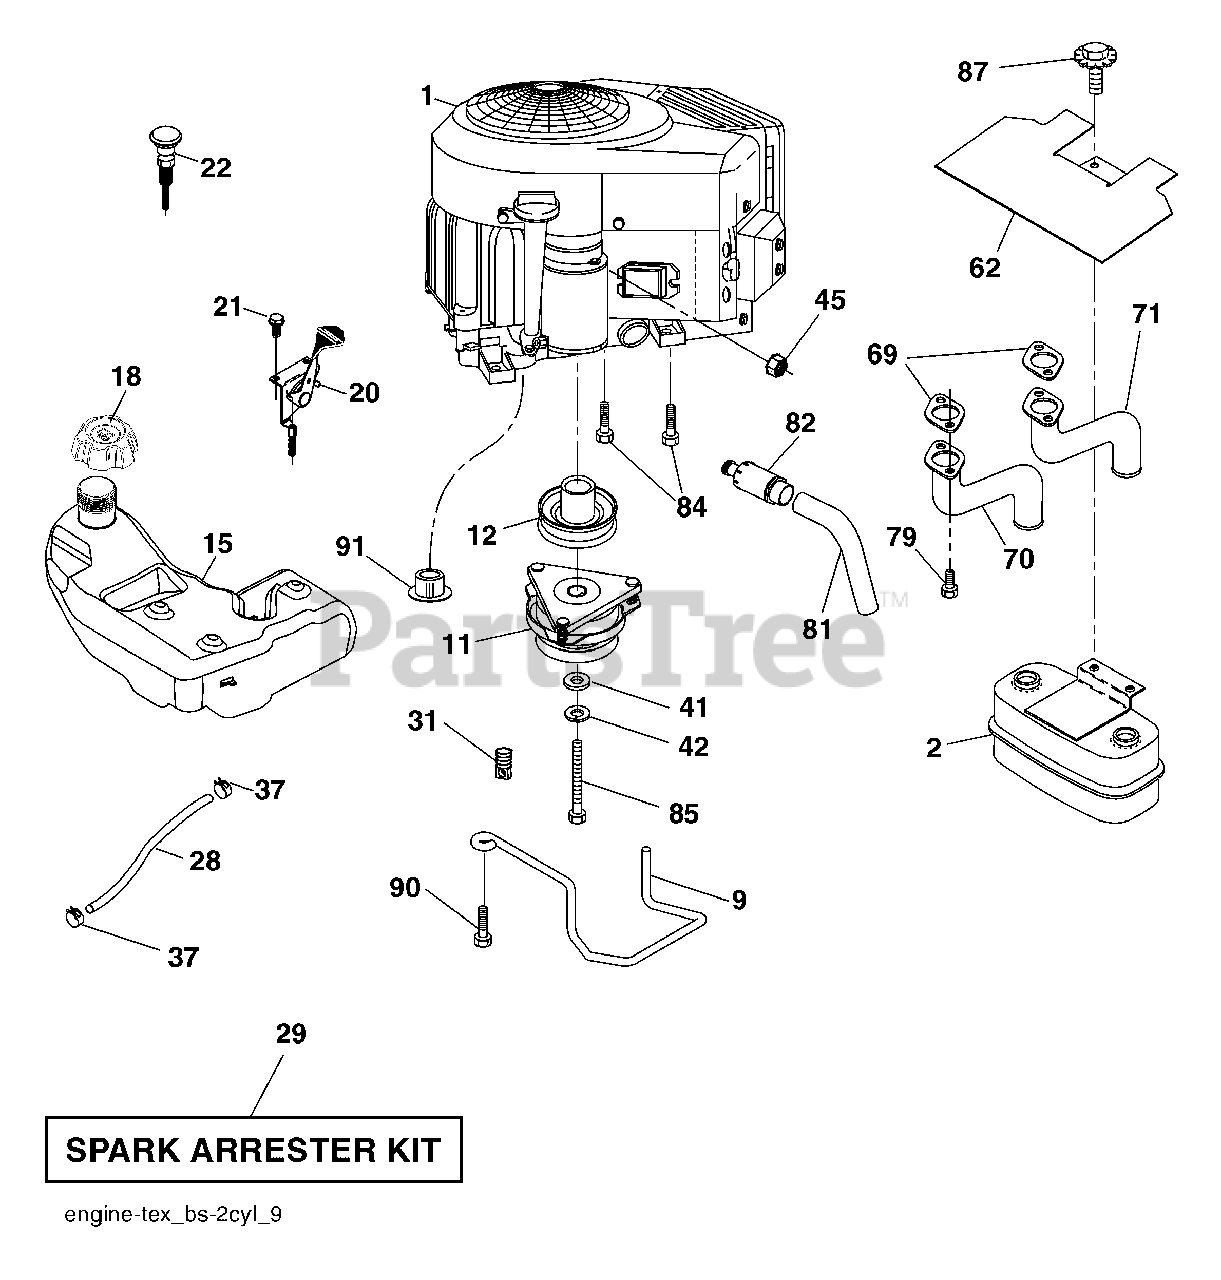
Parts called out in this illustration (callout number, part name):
9	Keeper Belt Engine
11	Clutch Electric
12	Pulley Engine
15	Tank Fuel 4.0
18	Cap Asm
20	Control Throttle
21	Screw #10 x .750 BOS Thread
22	Control Choke
28	Fuel Line
29	Spark Arrester Kit
31	Clip Push-In
37	Clamp Hose
41	Washer 1-1/2 OD x 15/32 ID x .250
42	Washer Lock 7/16
45	Nut Keps Hex 1/4-20 unc
62	Shield Heat Muffler
70	Tube Exhaust LH
71	Tube Exhaust RH
79	Screw Socket Head 5/16-18 x 1
81	Tube Drain Oil Easy
82	Plug Drain Oil
84	Screw 3/8-16 x 1 1/4
85	Bolt Hex 7/16-20 x 3.75 Gr. 5
87	Bolt 5/16-18 unc x 1 w/Sems
90	Screw 3/8-16 x 1
